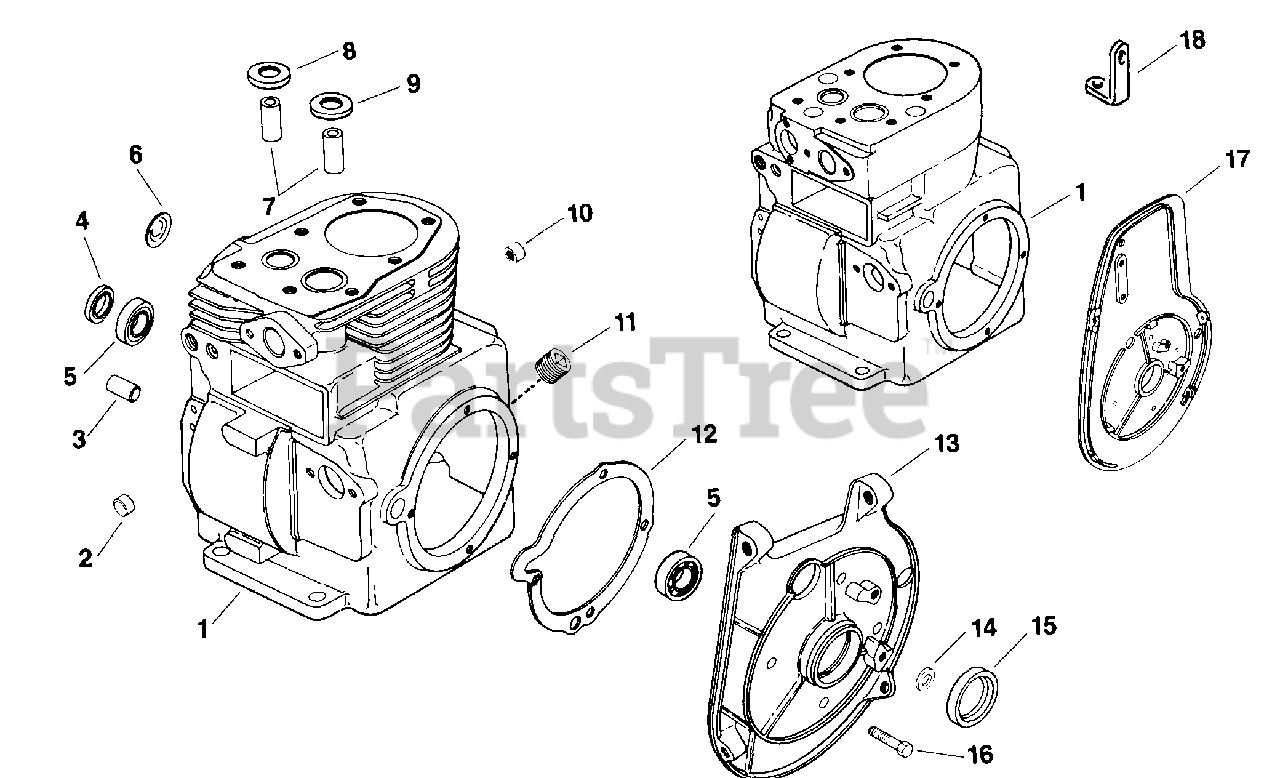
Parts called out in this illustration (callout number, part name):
1	Cylinder Block
5	BEARING - DISCONTINUED
6	PLUG, WELCH EXPANSION
8	INSERT - DISCONTINUED
10	BEARING
11	PLUG,PIPE 1/2 NPTF SQUARE HD USE 25 139 54-S
